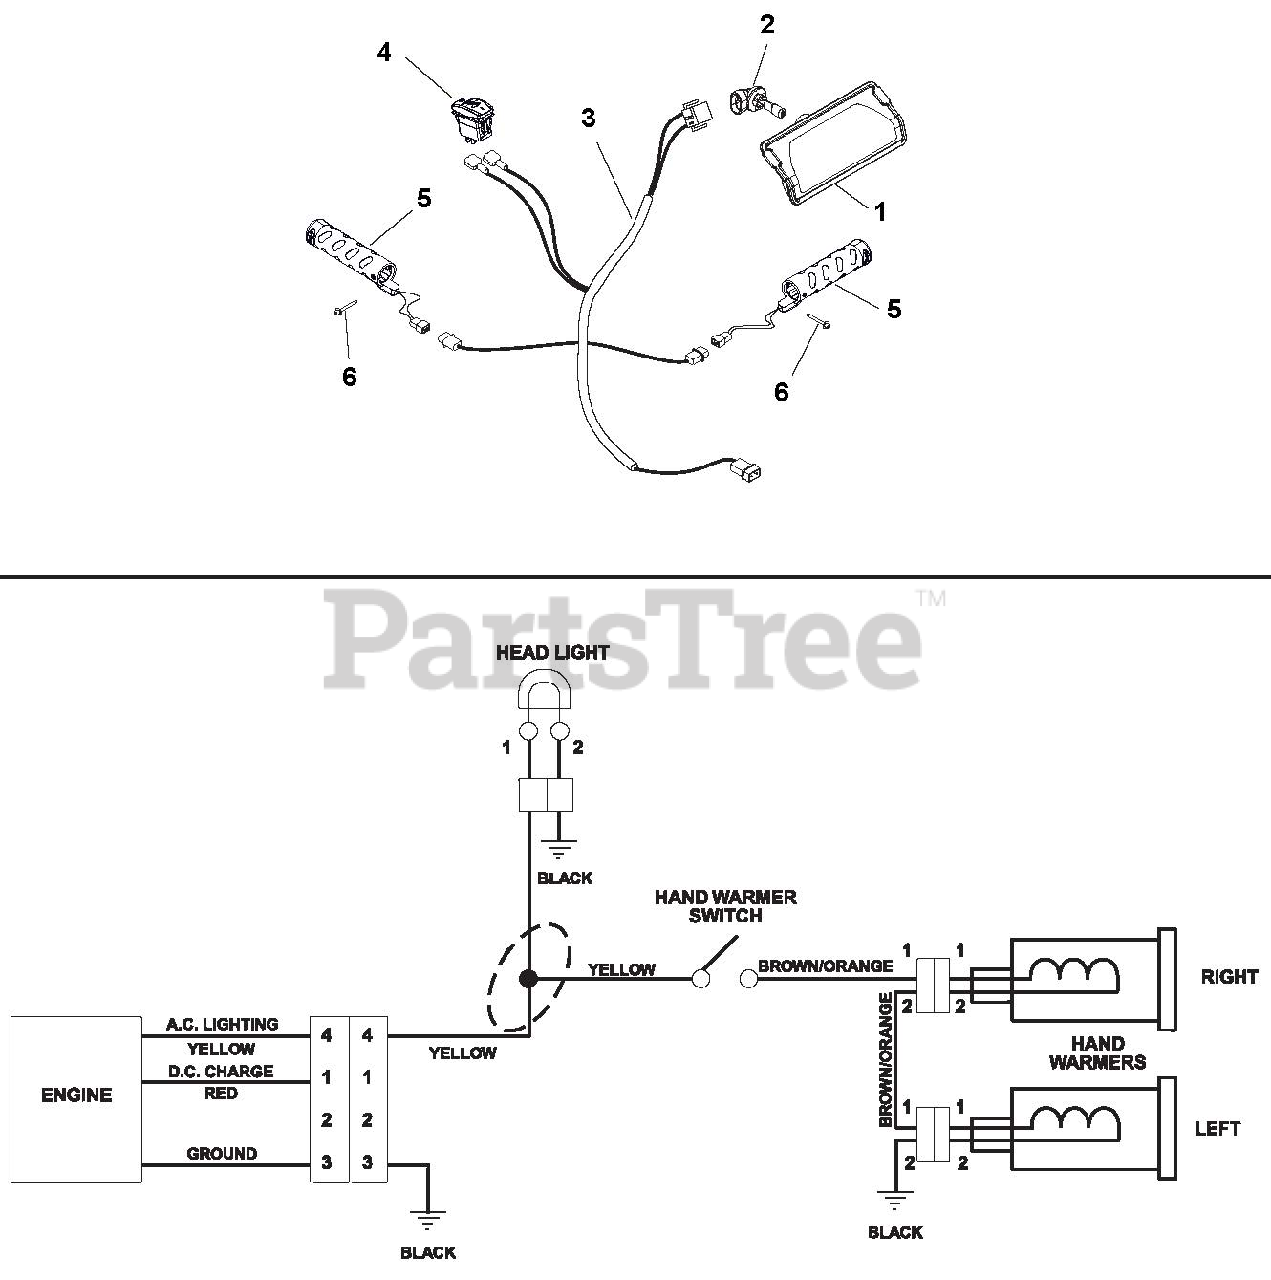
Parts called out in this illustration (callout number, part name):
1	HEADLIGHT ASY, HALO 20W 2SHOT
2	BULB, LIGHT-HALOGEN 20W
3	HARNESS, LIGHT & WARMER
4	SWITCH,ROCKER SPST-ON/OFF
5	GRIP,HEATED HANDLE-GRAY
6	RVT-POP #43 .125X.313 STL ZINC
